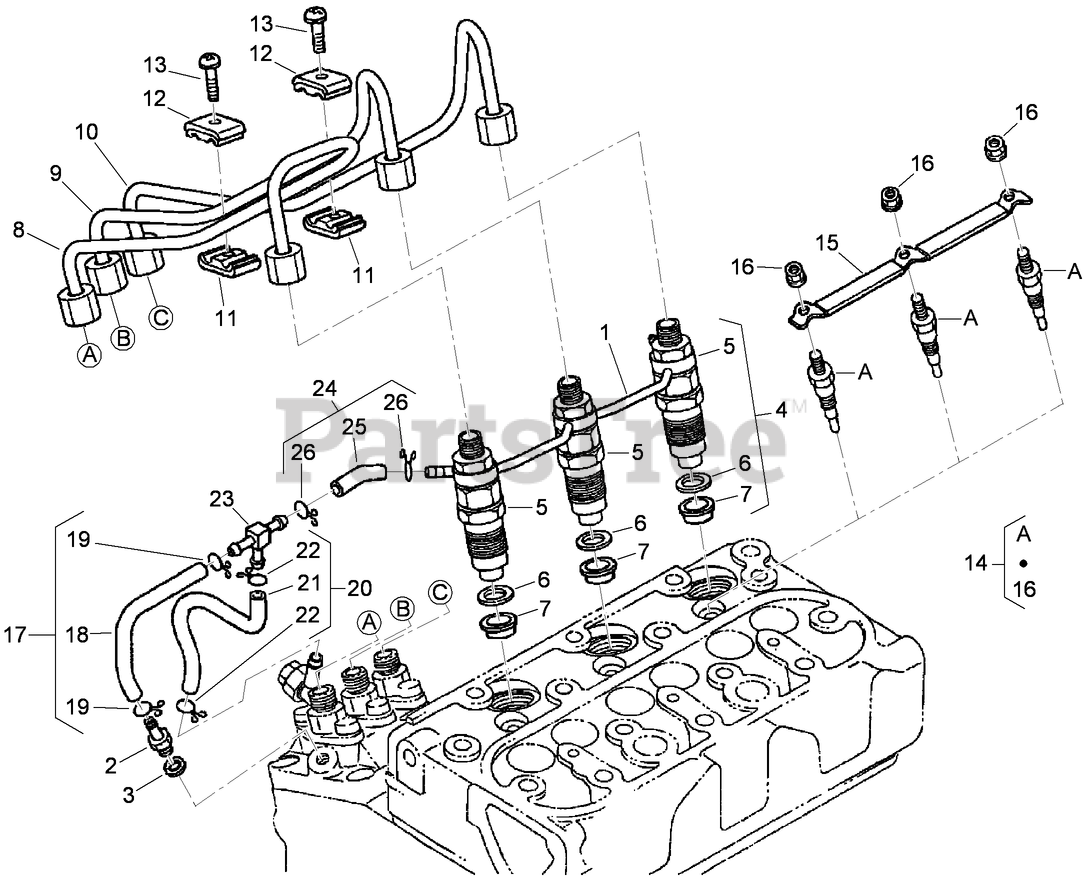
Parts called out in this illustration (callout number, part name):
1	OVER FLOW PIPE ASM
2	SCREW-BLEEDER, AIR
3	GASKET
4	NOZZLE HOLDER KIT
5	NOZZLE HOLDER ASM
6	GASKET
7	SEAL-HEAT
8	PIPE-INJECTION
9	PIPE-INJECTION
10	PIPE-INJECTION
11	CLAMP-PIPE
12	CLAMP-PIPE
13	SCREW (W/WASHER)
14	PLUG-GLOW
15	CORD-PLUG, GLOW
16	NUT-FLANGE
17	FUEL TUBE ASM
18	TUBE-FUEL
19	CLIP-PIPE
20	FUEL TUBE ASM
21	TUBE-FUEL
22	CLIP-PIPE
23	PIPE-JOINT, T
24	FUEL TUBE ASM
25	TUBE-FUEL
26	CLIP-PIPE
